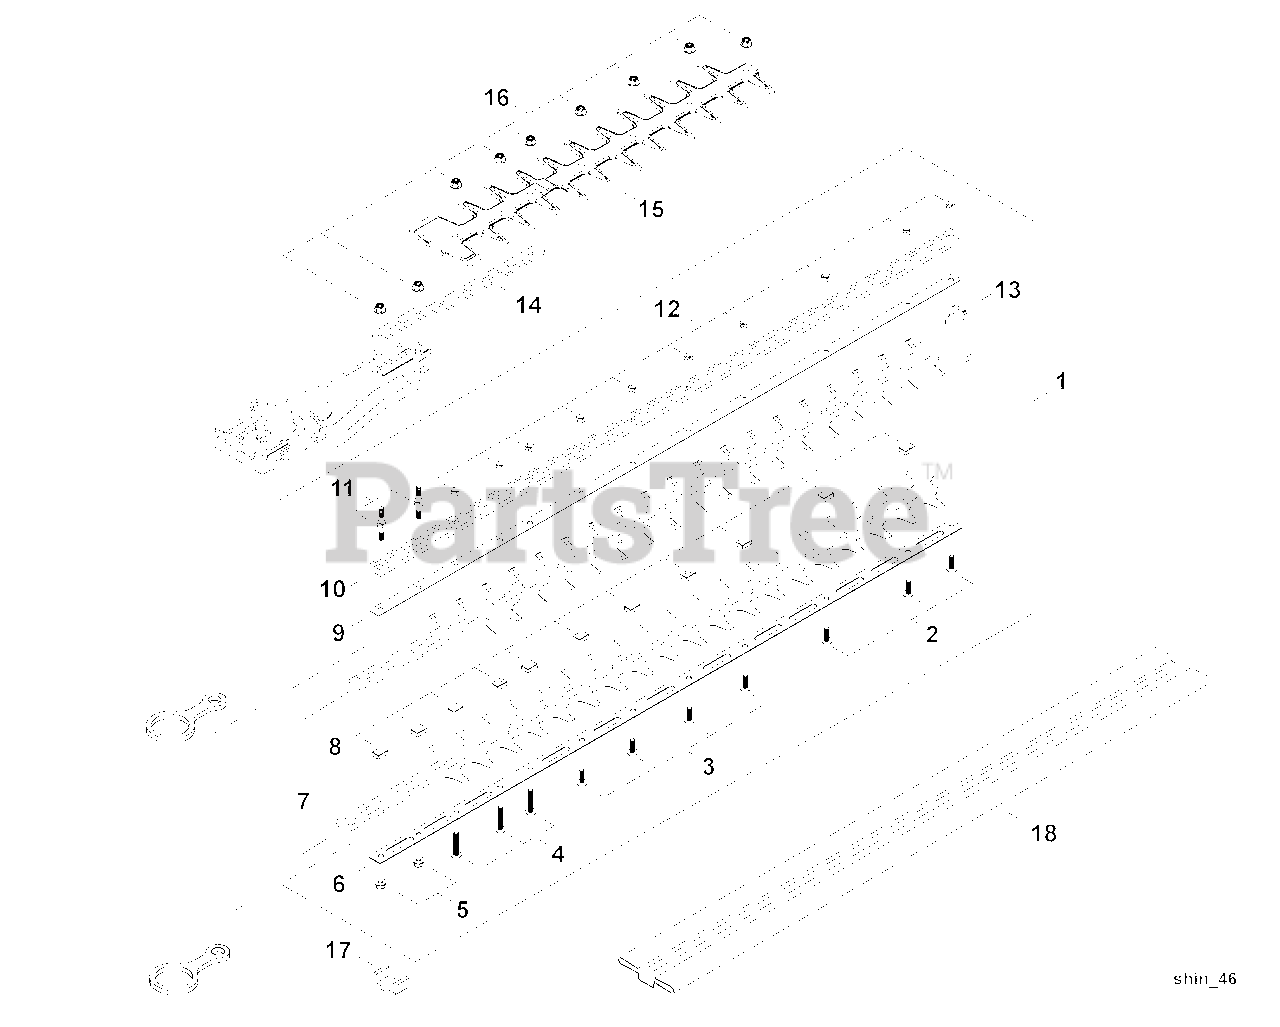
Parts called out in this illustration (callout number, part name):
1	CUTTER ASSY, 30"
2	BOLT M5×14
3	BOLT M5×22
4	BOLT M5×25
6	PLATE, LOWER
7	BLADE, 30"
9	PLATE, UPPER
10	GUIDE BAR, 30"
11	STUD, MOUNTING M5
12	NUT, LOCK M5
14	BRACKET, CUTTER
15	GUARD, CUTTER BLADE
17	PACKING, FELT
18	SCABBARD 30"
